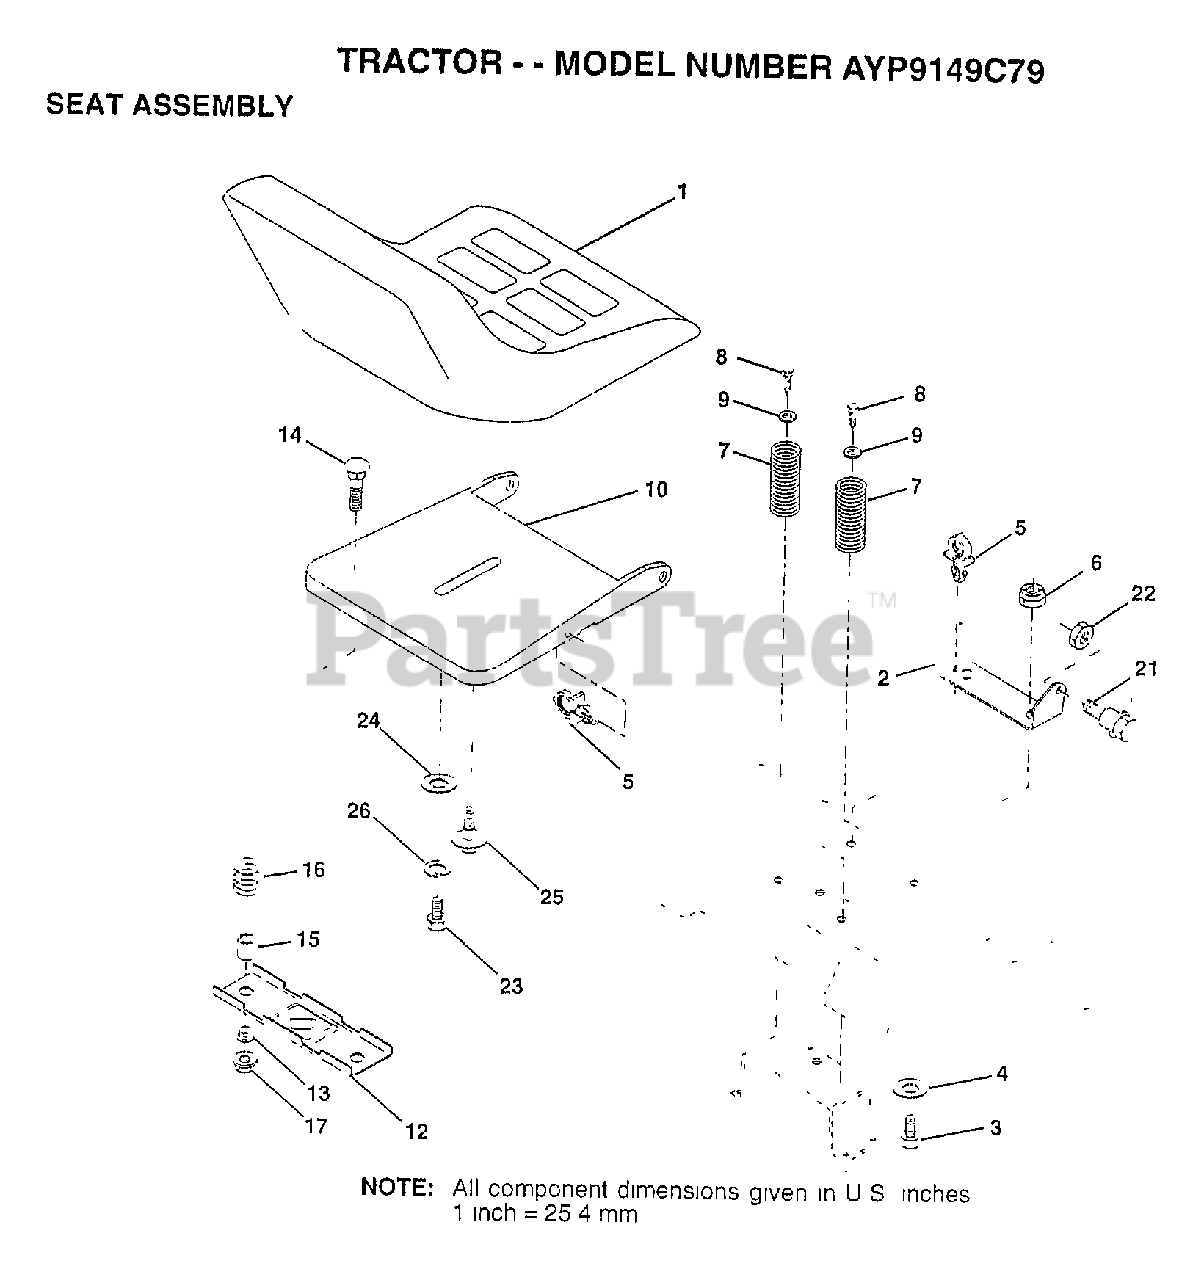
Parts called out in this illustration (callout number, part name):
2	BRACKET PVT SEAT
3	BOLT
4	WASHER PM
5	CLIP.PUSH-IN.HING
6	NUT
7	SPRING COMPRESSIO
8	SCREW GTV
9	WASHER
10	PAN-SEAT
12	BRKT SWITCH
13	BUSHING
14	BOLT, CARRIAGE
15	SPLIT SPACER
16	SPRING
21	"BOLT,SHOULDER"
22	NUT
23	BOLT
24	WASHER
25	"BOLT,SHOULDER"
26	LOCKWASHER
